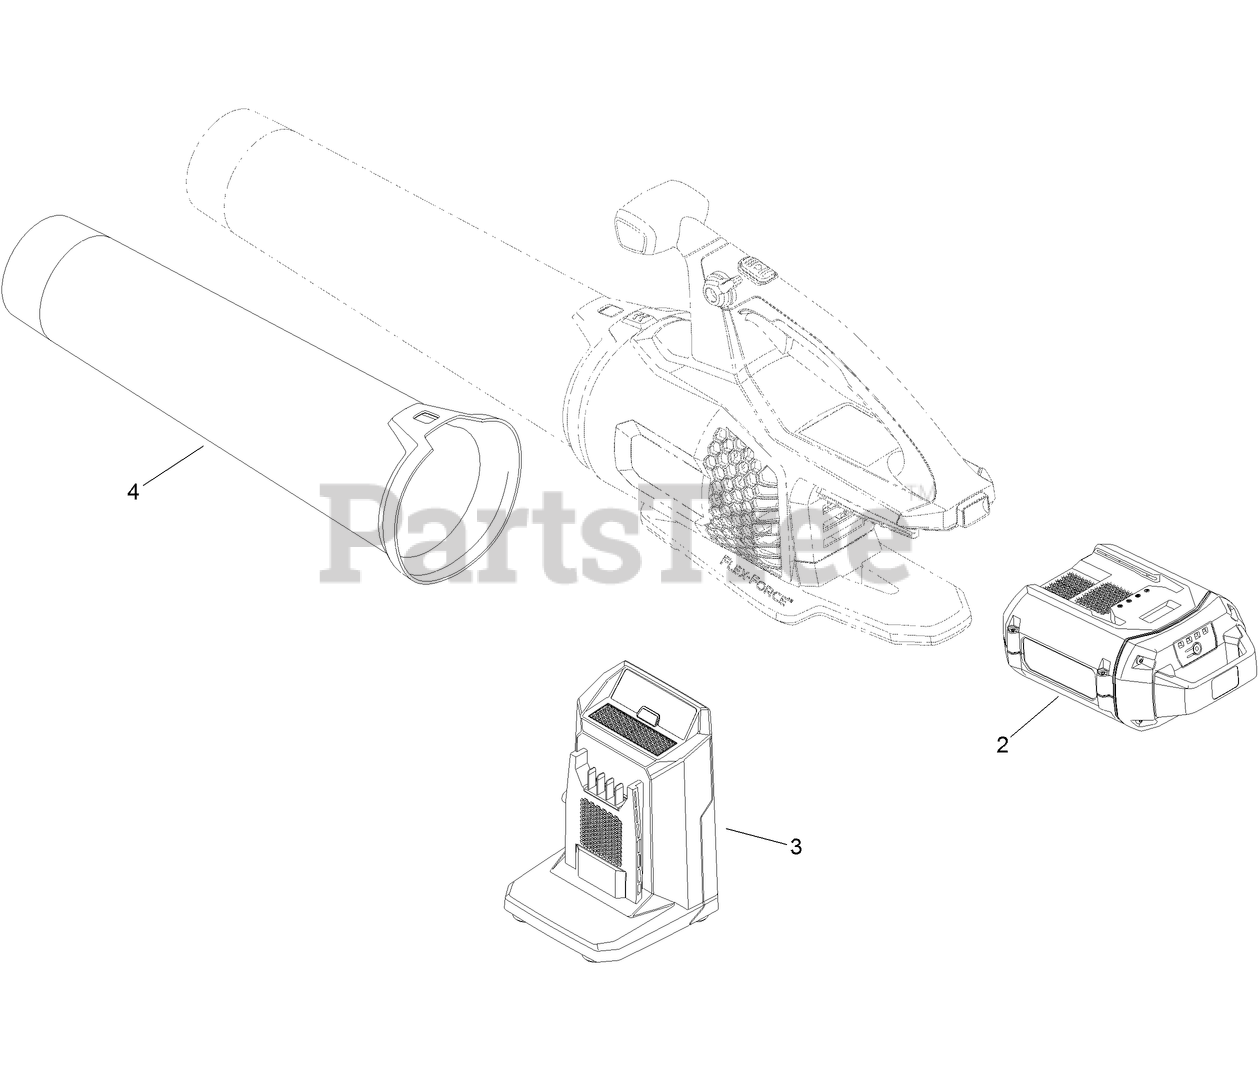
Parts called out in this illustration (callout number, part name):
2	BATTERY-LI ION, 60V 2.5 AH
3	CHARGER-BATTERY, 60V 2 AMP
4	TUBE-BLOW
